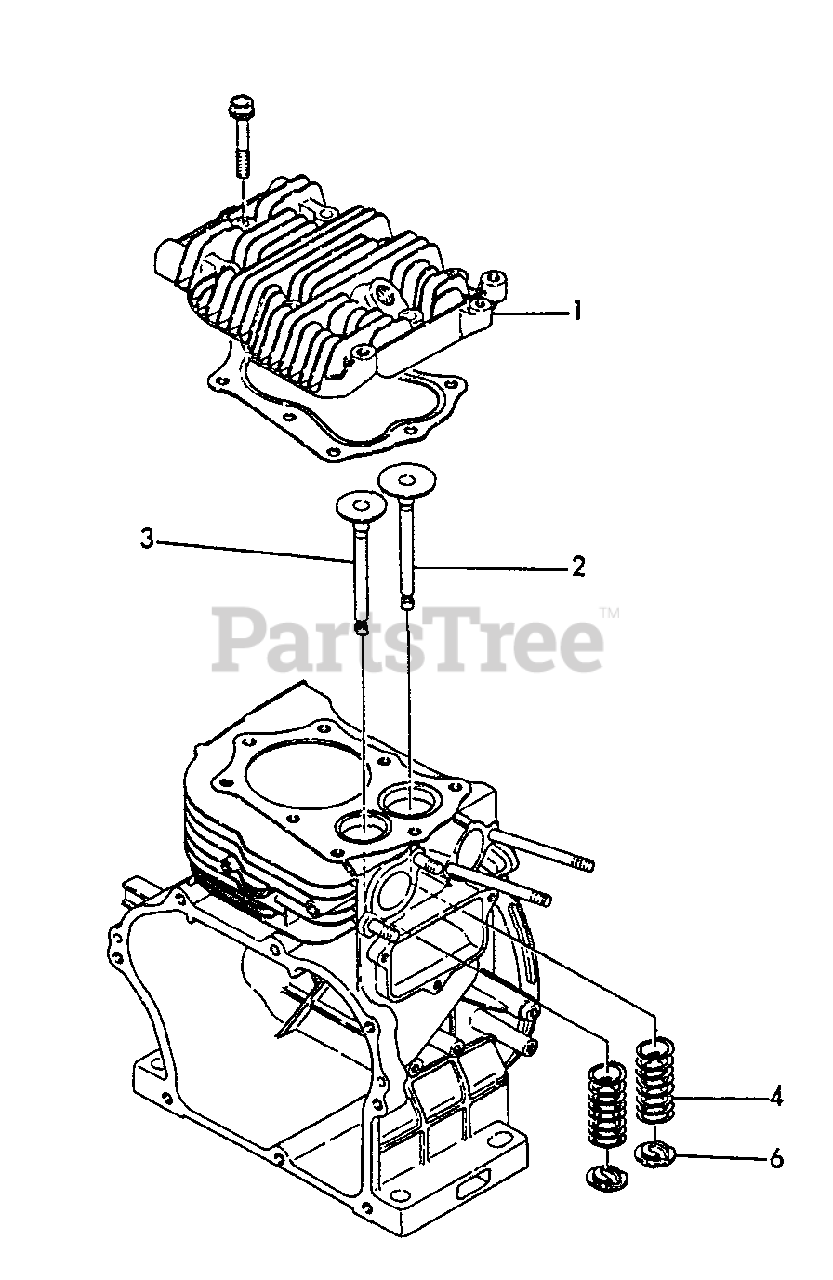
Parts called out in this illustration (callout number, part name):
1	HEAD, CYLINDER
2	VALVE, INTAKE
3	VALVE, EXHAUST
4	SPRING, VALVE
